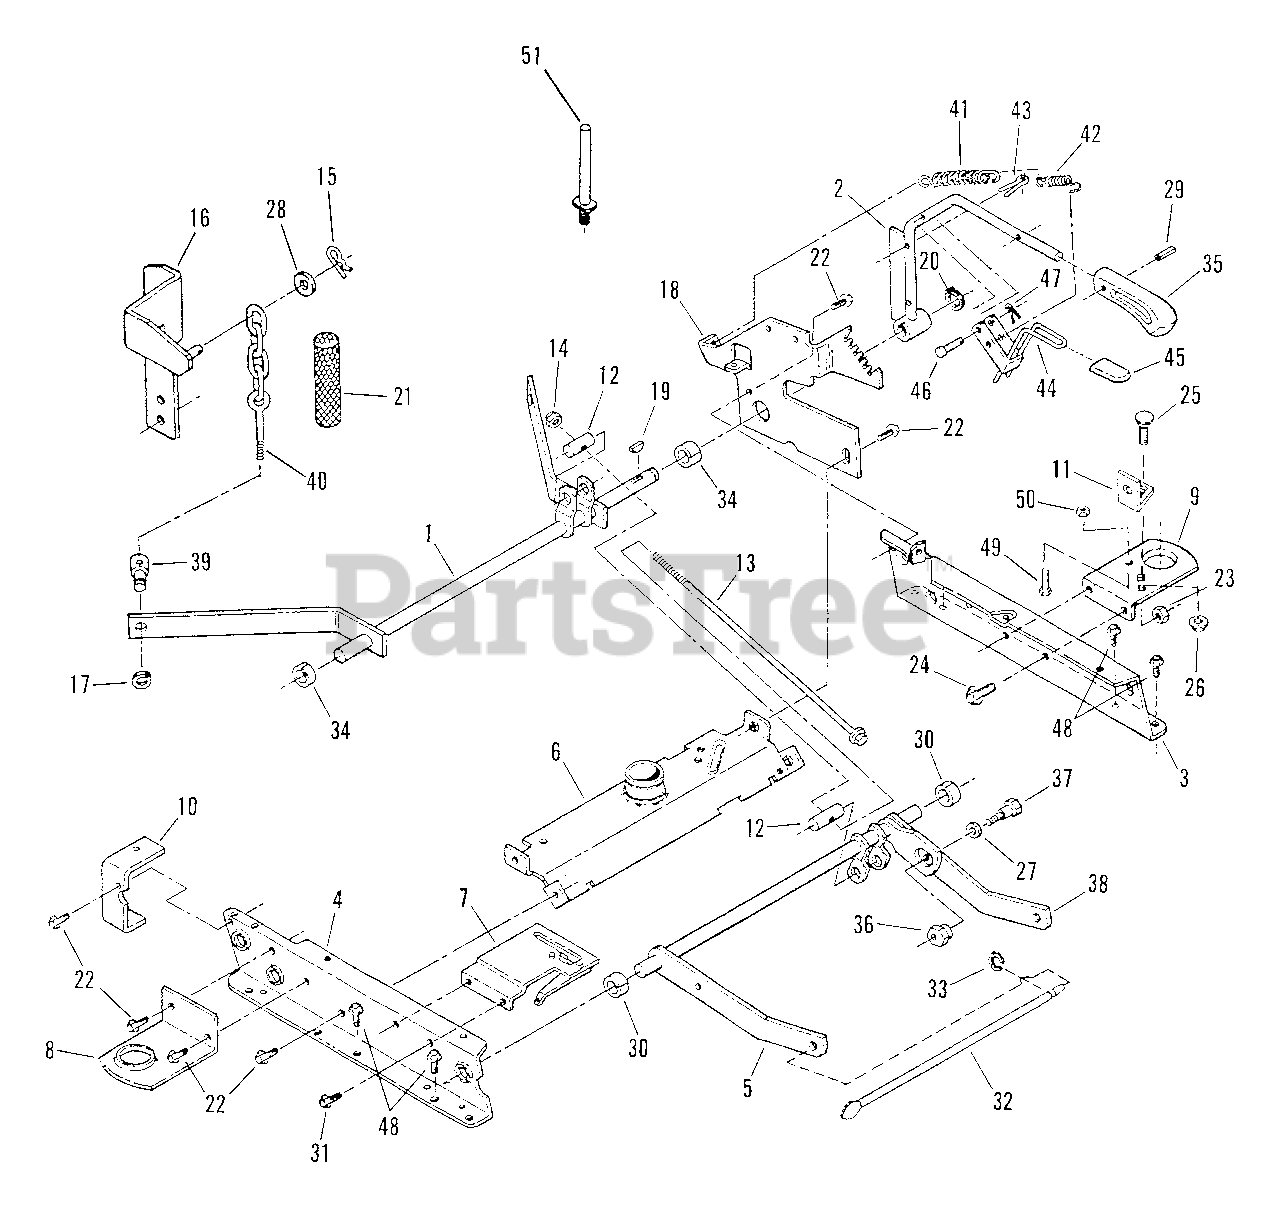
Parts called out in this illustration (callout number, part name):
1	ASSEMBLY, Rear Lift Arm
2	LEVER, Height Adjustment Lift
3	RAIL, Left Half
4	RAIL, Right Half
5	STRUCTURE, Front Lift Arm
6	BRACE, Weldment
7	ASSEMBLY, Clutch Plate
8	SPINDLE, Brace (Right)
9	SPINDLE, Brace (Left)
10	BRACKET, Cover
11	ANCHOR
12	CLEVIS, Timing Rod
13	ROD, Leveling
14	NUT, 3/8-24 Hex Top Lock
15	PIN, 3/32 x 1-3/16 Cotter
16	DECK-WING, Rear (Right)
17	RING, 5/8" External Retaining
18	QUADRANT, Lift Lever
19	KEY, 3/16 x 7/8" Woodruff
20	RING, 3/4 Retaining
21	COVER, Chain
22	SCREW, 3/8-16 x 3/4" Self-Tapping
23	NUT, 3/8-24 Hex Lock
24	SCREW, 3/8-24 x 3/4" Hex Cap
25	BOLT, 5/16-18 x 3/4" Carriage
26	NUT, 5/16-18 Hex Flange Lock
27	WASHER, 3/8 Internal Tooth Lock
28	WASHER, 3/8" Flat
29	PIN, 3/16 x 3/4" Roll
30	RING, Red
31	SCREW, 5/16-18 x 1/2" Self-Tapping
32	SUPPORT, Rod
33	RING, Retaining
34	RING, Blue
35	GRIP, Height Adjustment Lever
36	ECCENTRIC, Leveling
37	BOLT, 3/8-24 x 3/4" Shoulder
38	ARM, Front Lift (Left Side)
40	ASSEMBLY, Bolt & Chain Adjuster
41	SPRING, Extension
42	SPRING, Latch
43	PIN, 3/16 x 1-1/2" Cotter
44	LATCH
45	GRIP, Lift Latch
46	PIN, 1/4 x 1-1/4" Clevis
47	PIN, 1/16 x 3/4" Cotter
48	BOLT, 5/16-18 x 5/8" Hex Flange Lock
49	SCREW, 3/8-24 x 1" Hex Head Cap (Gr. 5)
50	NUT, 3/8-24 Hex Lock
51	BELT GUIDE, 6"
